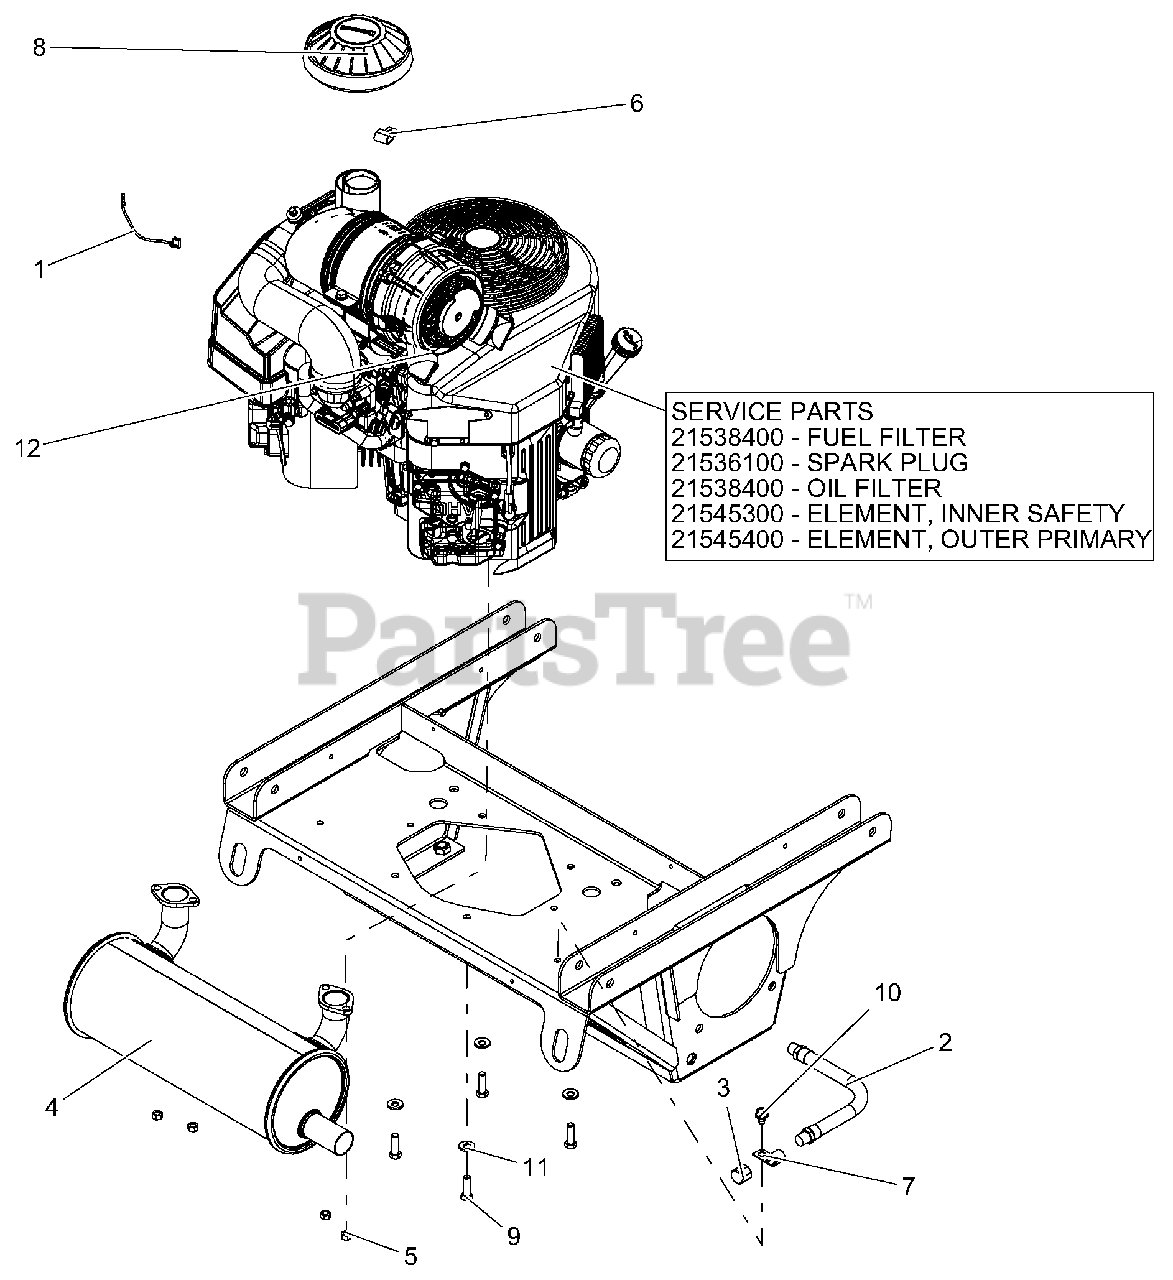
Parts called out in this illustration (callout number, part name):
1	LEAD - STARTER SOLENOID
2	HOSE, HYD .38-11-0K M6N0-M6N0
3	PIPE, CAP 3/8 NPT FEMALE
4	MUFFLER - 34HP KAWASAKI VERT
5	NUT-LK-TOP M8-1.25 YWZC
6	CLAMP, J
8	CAP, AIR CLEANER INTAKE (2")
9	BLT-HEX .38-16X1.25 GR5 YWZC NYTORQ
10	SCR-TAP .38-16X.50 HWH TR YWZ
11	WSHR, 3/8" SPRING DISC
12	ENGINE, KAWASAKI FX1000
